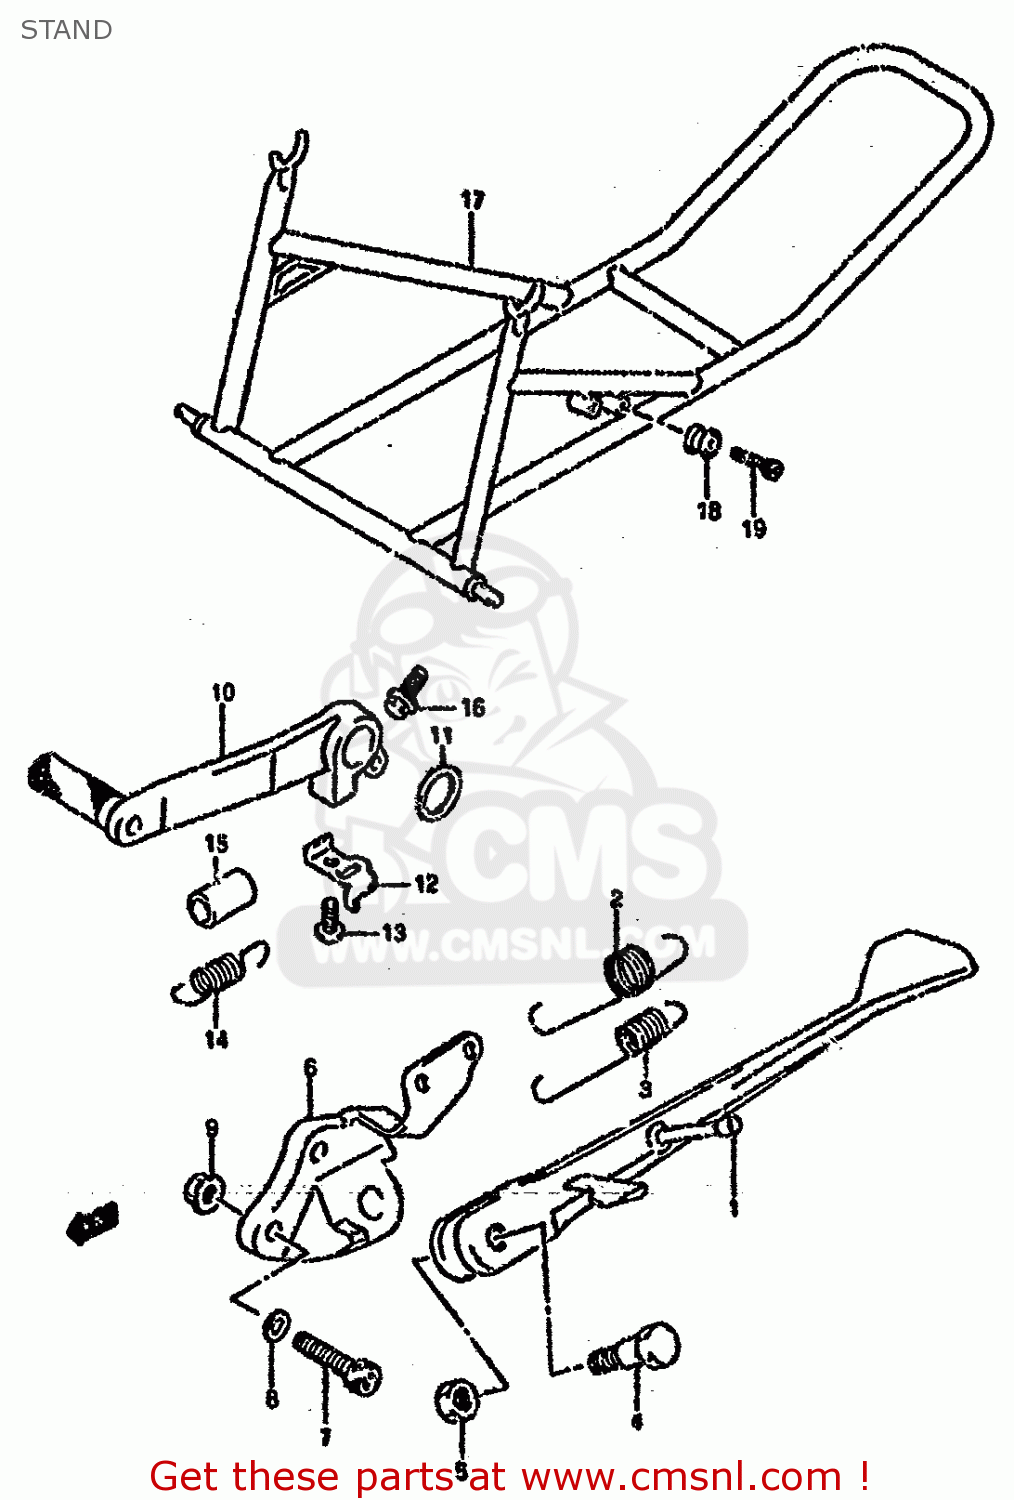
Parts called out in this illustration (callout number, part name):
1	STAND,PROP
2	SPRING
3	SPRING
4	BOLT(10X38)
5	NUT
6	BRACKET,PROP STAND
7	BOLT
8	WASHER
9	NUT
10	PEDAL,BRAKE
11	WASHER(18X24X1)
12	HOOK,RETURN SPRING
13	BOLT
14	SPRING
15	TUBE,BRAKE SPRING GUIDE
16	BOLT
17	STAND ASSEMBLY,REAR
18	HOLDER,STAND
19	BOLT
